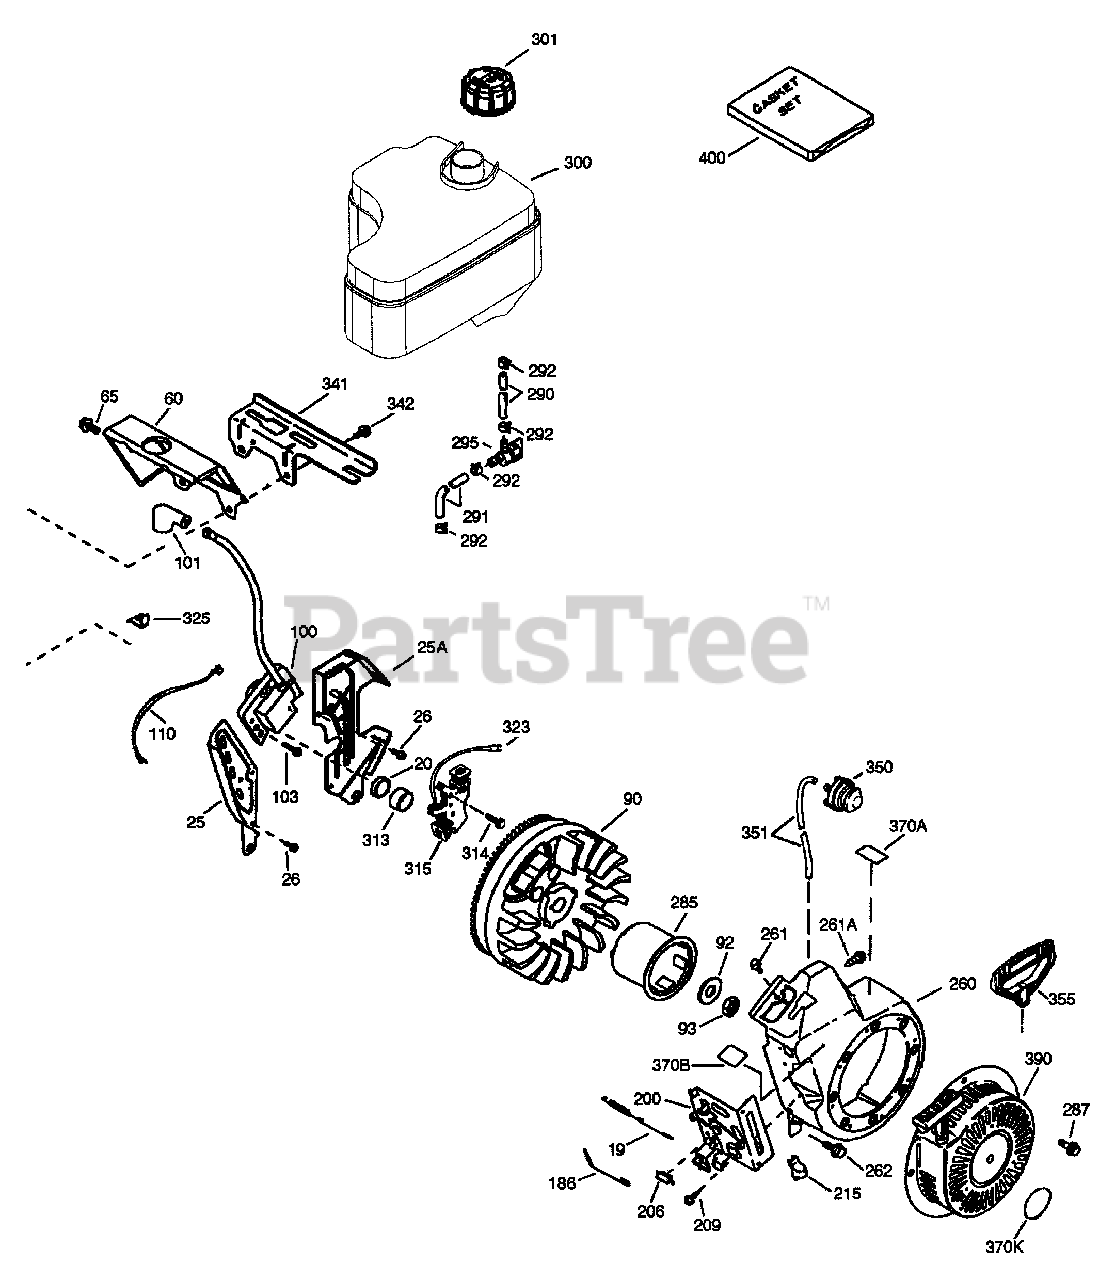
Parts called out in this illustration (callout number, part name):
19	Extension Spring
25	Air Baffle (Left)
25A	Air Baffle (Right)
26	Screw, 10-24 x 9/16"
60	Blower Housing Extension
65	Screw, 10-24 x 9/16"
92	Belleville Washer
93	Flywheel Nut
100	Solid State Ignition
101	Spark Plug Cover
103	Screw, Torx T-15, 10-24 x 15/16"
110	Ground Wire
186	Governor Link
200	Control Bracket
209	Screw, 10-32 x 1/2"
215	Control Knob
260	Blower Housing
261	Screw, 1/4-20 x 31/64"
261A	Screw, 10-32 x 1/2"
262	Screw, 1/4-20 x 31/64"
285	Starter Cup
287	Screw, 1/4-20 x 31/64"
290	Fuel Line
291	Fuel Line
292	Fuel Line Clamp
295	Fuel Shut-Off Valve
300	Fuel Tank
301	Fuel Cap
314	Screw, 1/4-20 x 3/4"
315	Alternator Coil (18 Watt)
325	Wire Clip
341	Fuel Tank Bracket
342	Screw, 1/4-20 x 7/8"
350	Primer Assembly
351	Primer Line
355	Starter Handle (Mitten Grip)
370A	Lubrication Decal
370B	Control Decal
370K	Starter Decal
390	Rewind Starter
400	Gasket Set
